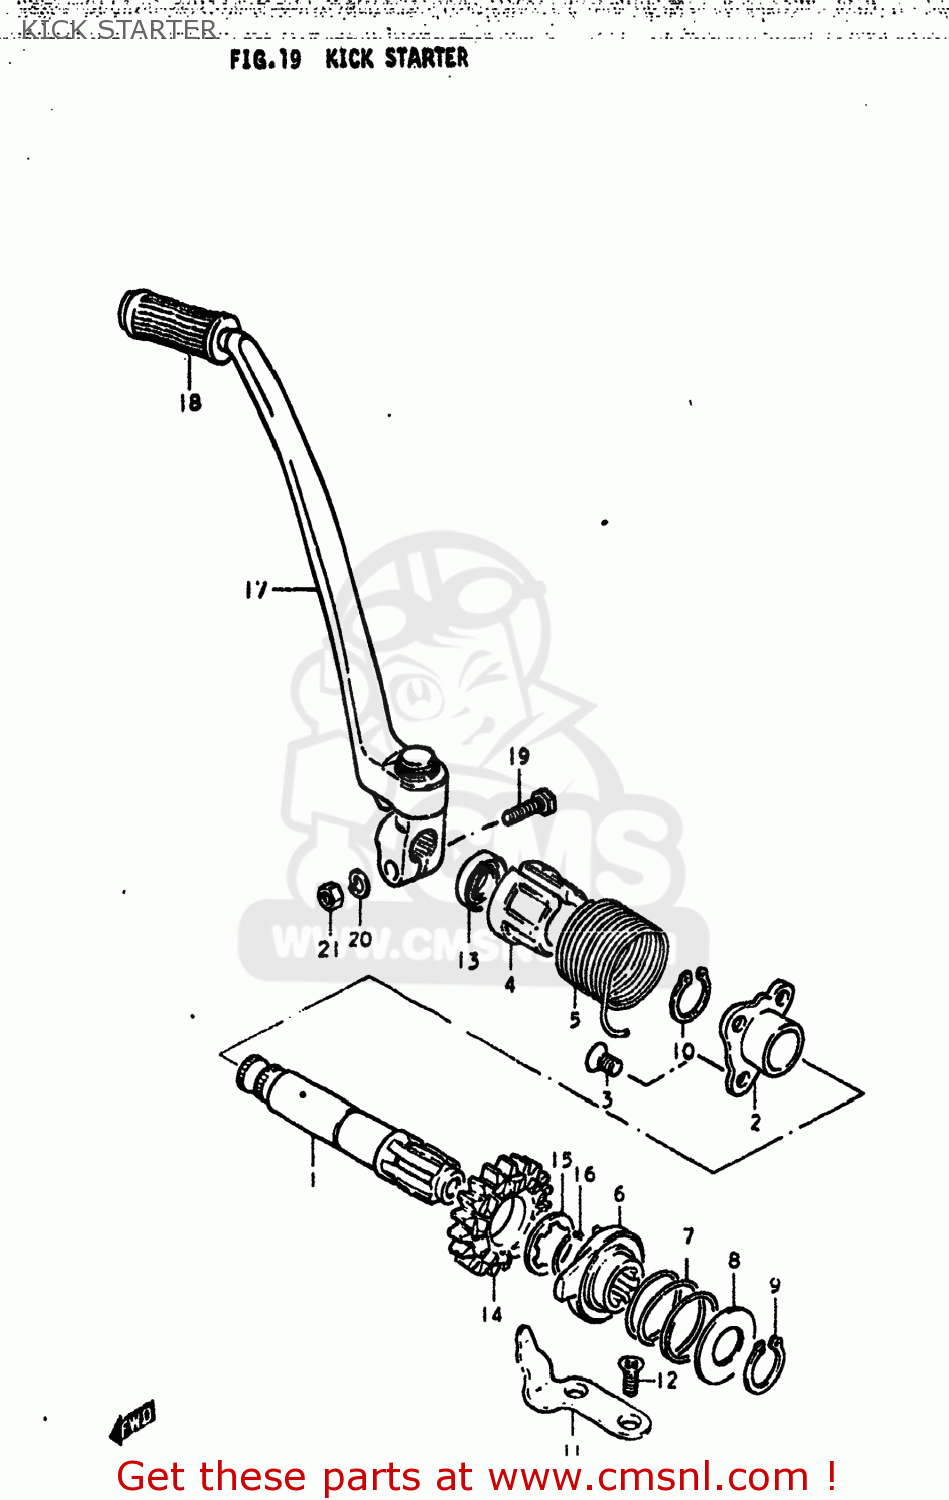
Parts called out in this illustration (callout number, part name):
1	SHAFT,KICK STARTER
2	HOLDER,KICK STARTER SHAFT
3	SCREW
4	GUIDE,STARTER SHAFT SPRING
5	SPRING
6	STARTER,KICK
7	SPRING
8	WASHER
9	CIRCLIP
10	CIRCLIP
11	GUIDE,STARTING SPRING
12	SCREW
13	SEAL,OIL(20X27X5)
14	GEAR,KICK STARTER DRIVE
15	WASHER,LOCK
16	CIRCLIP
17	LEVER ASSY,KICK STARTER
18	RUBBER,KICK STARTER PEDAL
19	BOLT,M10X1.25X
20	LOCK WASHER
21	NUT
